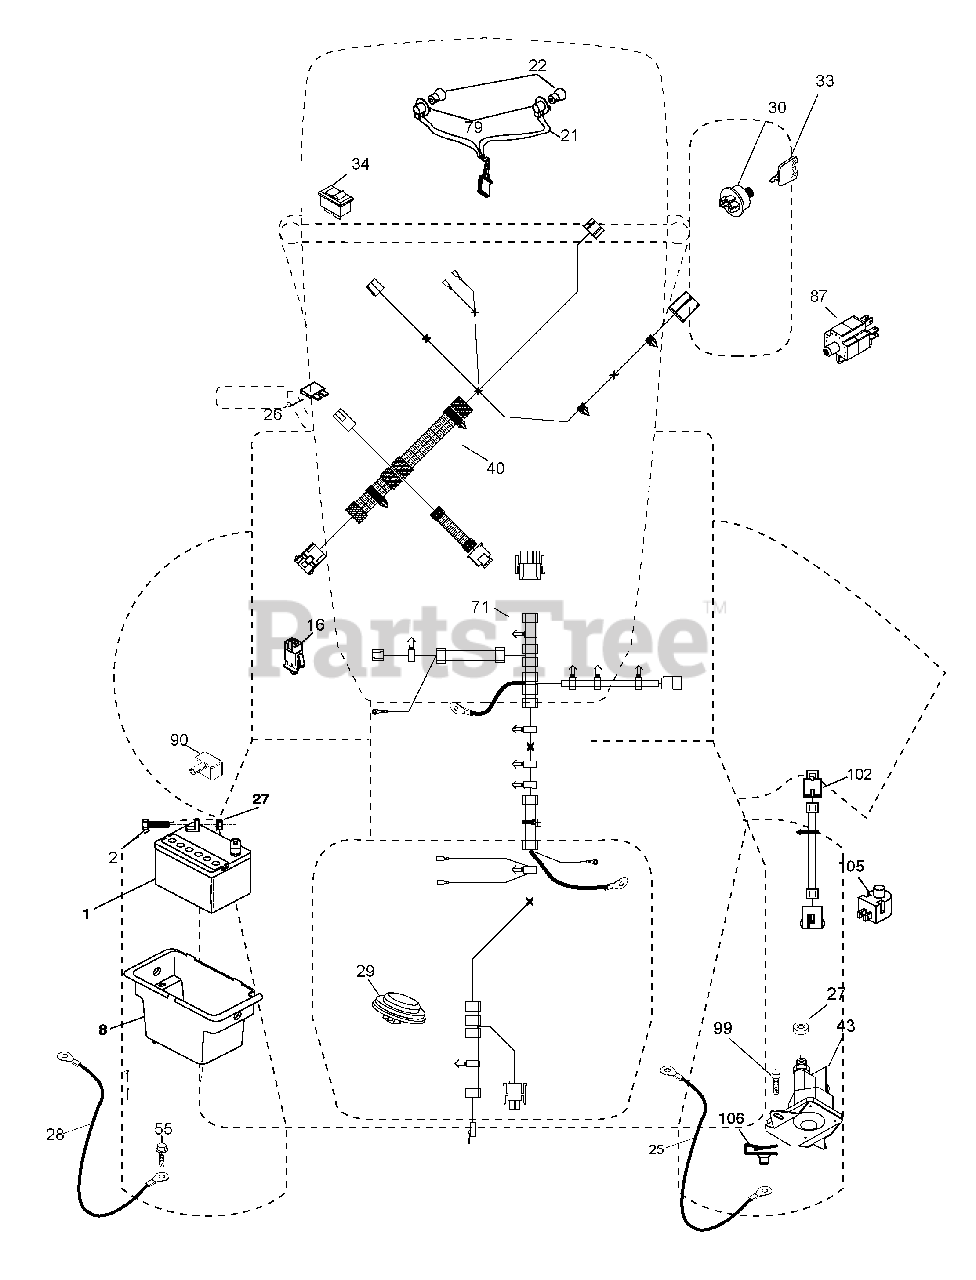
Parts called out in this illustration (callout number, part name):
1	Battery
2	Bolt Hex Head 1/4-20 x 3/4
8	Box Battery
16	Switch Interlock Push-In
21	Harness Socket Light w/4152J
22	Bulb Light
25	Cable Starter
27	Nut Keps Hex 1/4-20 unc
28	Cable, Ground
29	Switch, Seat
30	Switch, Ignition
33	Key/Chain
34	Switch Light/Reset
40	Harness Ignition Dash
43	Solenoid
55	Screw Thdrol 5/16-18 x 3/4 TYTT
71	Harness Ignition Chassis
79	Socket Asm Bulb Twistlock
87	Switch Interlock Clutch Cable
90	Cover Terminal Battery
99	Screw 1/4-20 x 3/4
102	Harness Pigtail
105	Switch Reverse
106	Palnut 1/4" Lugs
